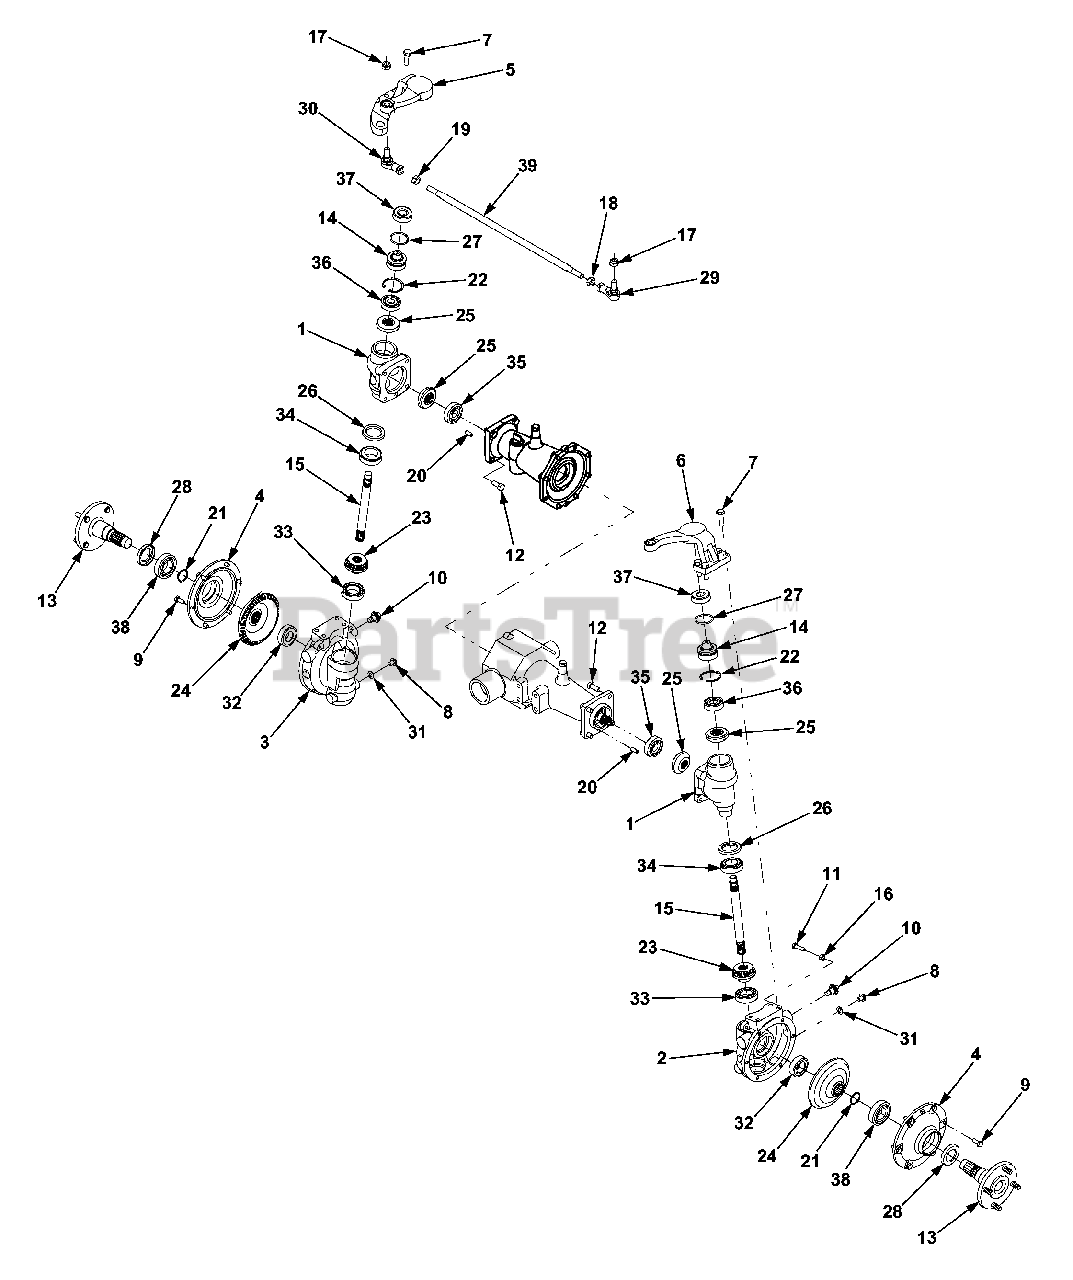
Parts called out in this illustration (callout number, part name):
1	Housing, Kingpin
2	Housing, Axle Drop, RH
3	Housing, Axle Drop, LH
4	Cover, Axle
5	Arm, Steering, LH
6	Arm, Steering, RH
7	Screw, Hex Cap, M10-1.5 x 35 GR8.8
8	Plug, Hex, 3/8-16 x .5
9	Screw, Hex Cap, M8-1.25 x 20 GR8.8
10	Plug, Screw, M14-1.5 x .827
11	Screw, Hex Cap, M8-1.25 x 30
12	Screw, Hex Cap, M10-1.5 x 25
13	Axle, Flange
14	Shaft, Stub
15	Shaft, Kingpin
16	Nut, Hex, M8-1.25
17	Nut, Hex Flange Lock, M12-1.75
18	Nut, Hex, M12-1.75 RH Thrd.
19	Nut, Hex, M12-1.75 LH Thrd.
20	Pin, Dowel, 8mm x 20mm
21	Ring, Retaining
22	Ring, Retaining
23	Gear, Bevel, 13T
24	Gear, Bevel, 34T
25	Gear, Bevel, 14T
26	Seal, Oil, 38mm x 55mm x 7mm
27	O-Ring, 40mm x 3mm
28	Seal, Oil, 35mm x 55mm x 8mm
29	Ball Joint, 12-1.75 RH
30	Ball Joint, 12-1.75 LH
31	Washer, Flat, .39 x .75 x .062
32	Bearing, Ball
33	Bearing, Ball
34	Bearing, Tapered Roller w/ Race
35	Bearing, Ball
36	Bearing, Ball
37	Bearing, Ball
38	Bearing, Ball
39	Rod, Tie, M12-1.75
